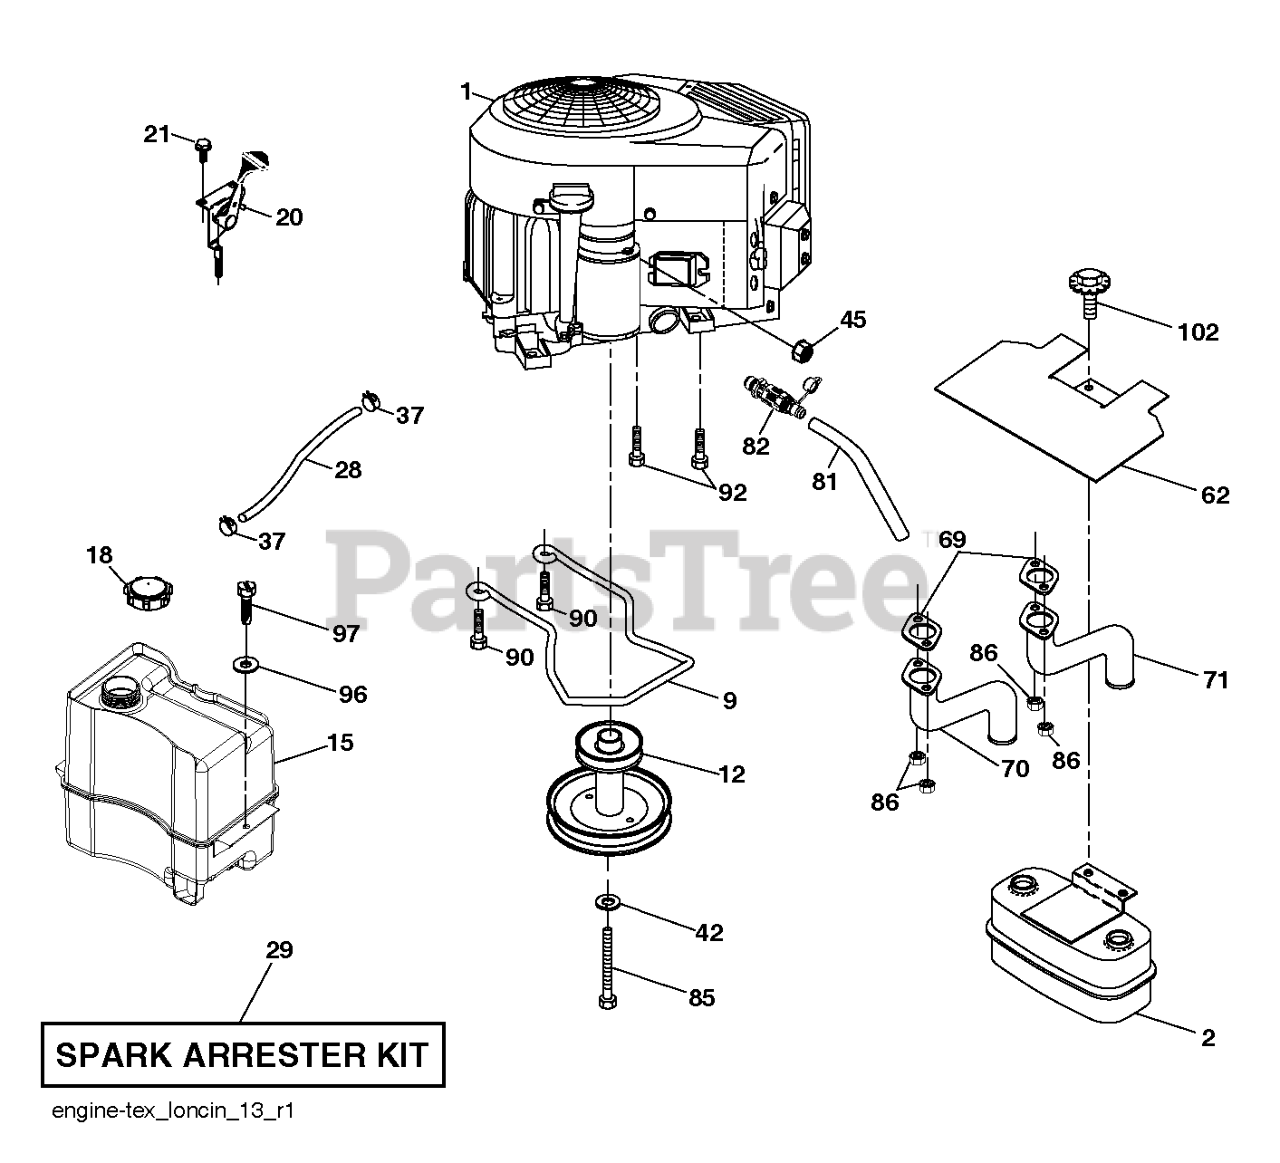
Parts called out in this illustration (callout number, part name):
2	MUFFLER.ASM.TWIN.MNTG.BRACKET
9	KEEPER.BELT.ENG.4.25"2.BLT.431
12	PULLEY.ENGINE
15	TANK.ASSEMBL.2.5GAL.NON-EPA
18	CAP ASM.FUEL.2.25"FR.
20	CONTROL.TH/CK.COBRA.B&S.TWN.BK
28	LINE.FUEL.20
29	KIT.SPARK ARRESTOR 794945 B&S
37	HOSE CLAMP
45	NUT HEXAGON WITH FLANGE, SERRA
62	SHIELD.HEAT.MUFFLER
81	TUBE, DRAIN OIL ASM.
82	VALUE.OIL.DRAIN
85	BOLT.HEX.7/16-20X4.GR5.1.5BLUE
86	NUT.HEX.FLANGE.TOPLOCK
90	SCREW 3/8-16X1
92	SCREW 3/8-16X1
97	SCREW HEXWSHR 1/4-20X3/4
102	SCREW
